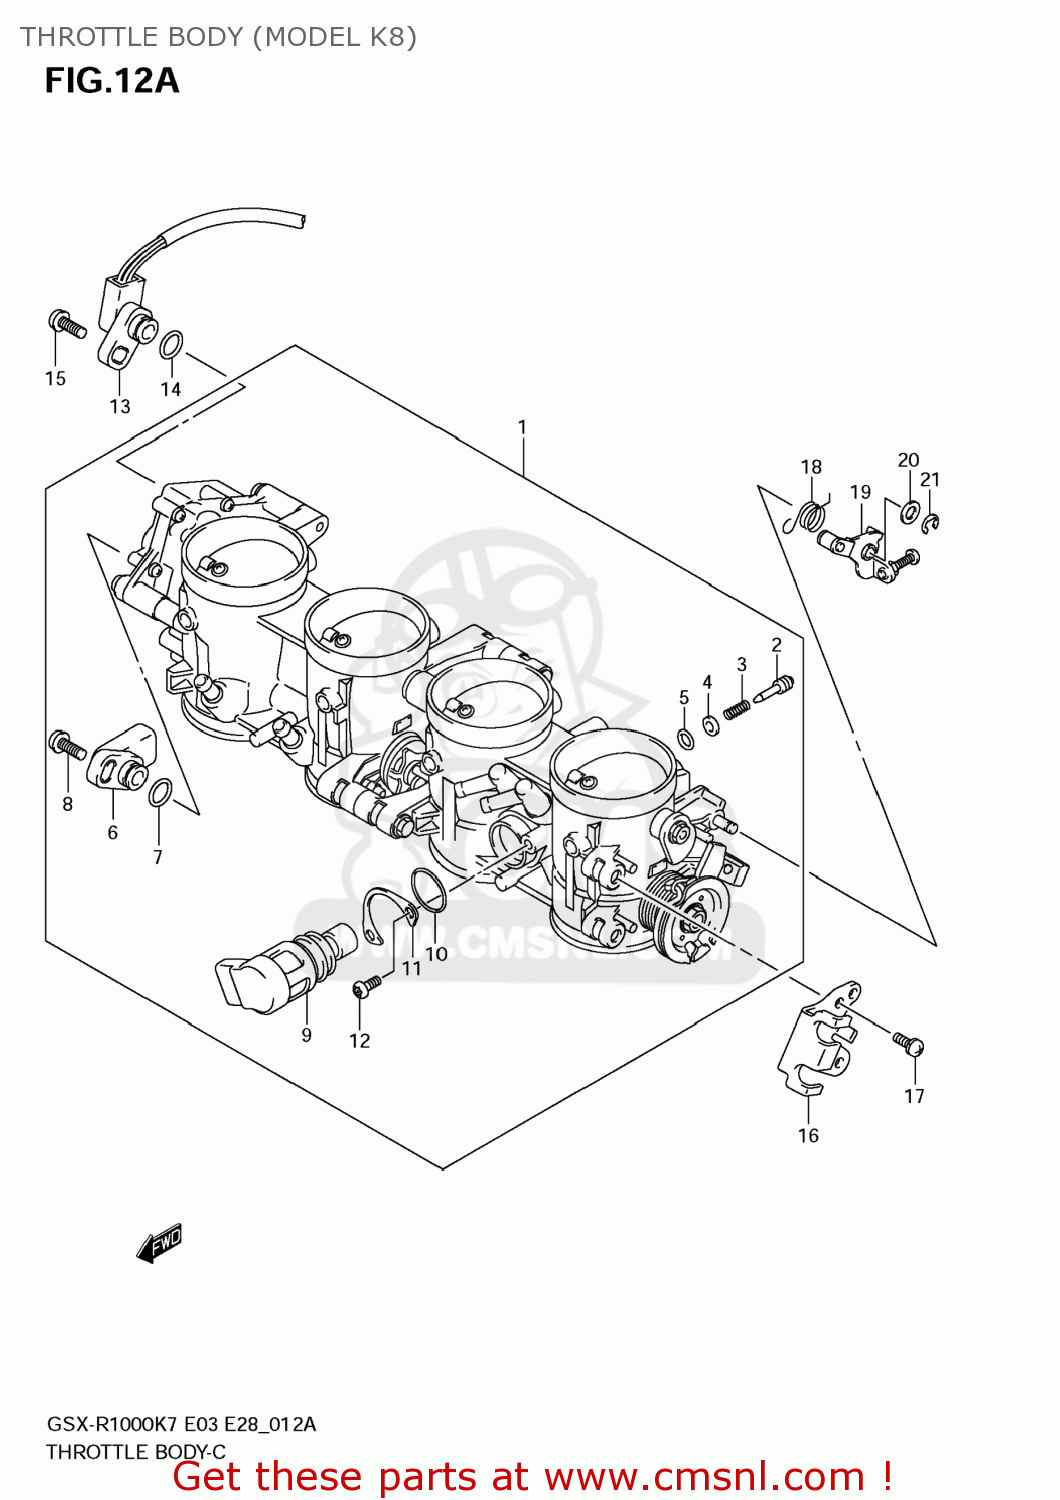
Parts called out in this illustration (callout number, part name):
1	BODY ASSY,THROTTLE
2	SCREW,AIR ADJUST
3	SPRING
4	WASHER
5	O RING
6	SENSOR ASSY,THROTTLE MAIN
7	O RING
8	SCREW
9	VALVE ASSY,ISC
10	O RING
11	PLATE,ISC VALVE
12	SCREW
13	SENSOR ASSY,TH
14	O RING
15	SCREW
16	PLATE,STAY
17	SCREW
18	SPRING
19	LEVER ASSY,LINK
20	WASHER
21	E CLIP
